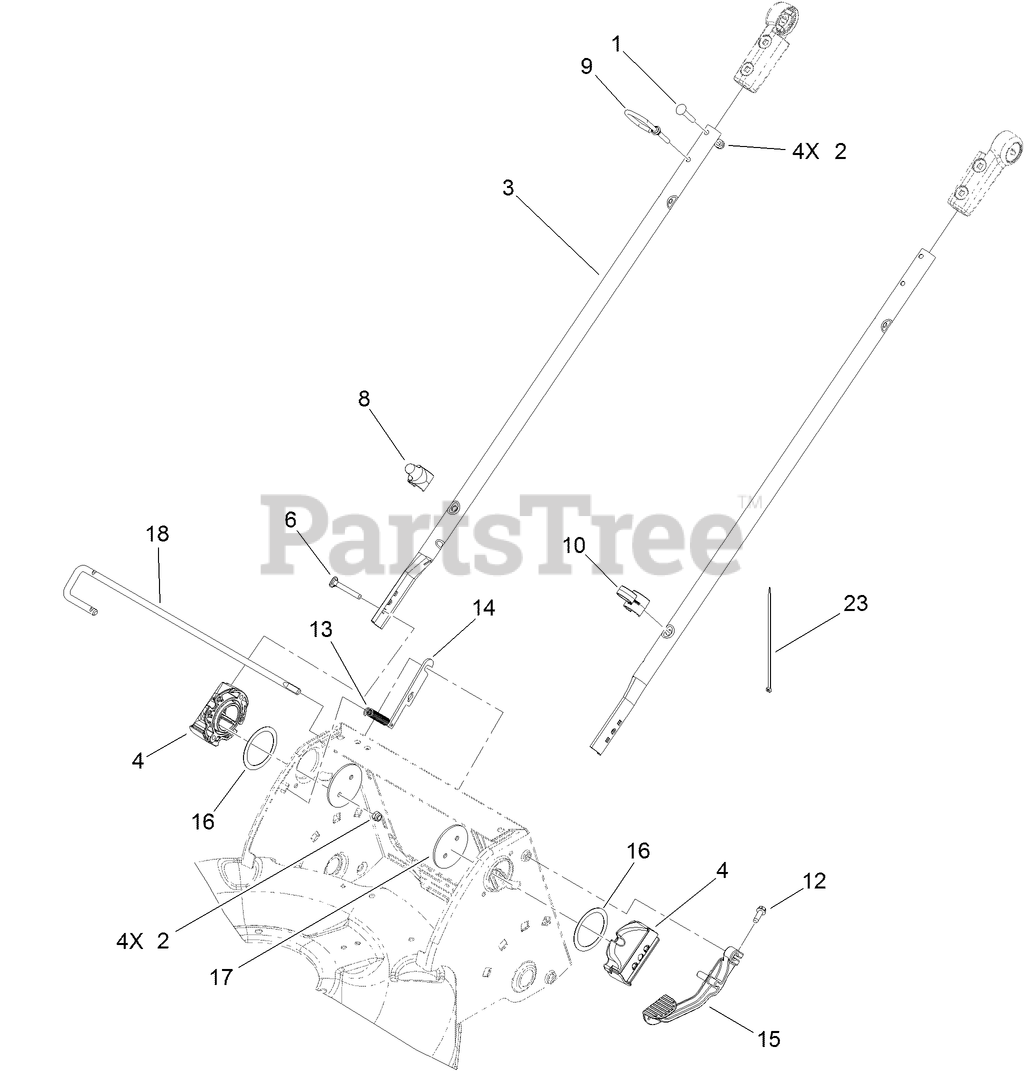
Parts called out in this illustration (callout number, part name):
1	SCREW-CARR
2	NUT-LOCK, NI
3	TUBE-LOWER
4	MOUNT-HANDLE
6	SCREW
8	GUIDE-ROPE, LOWER
9	GUIDE-ROPE, UPPER
10	GUIDE-CABLE
12	SCREW-HWHTF
13	SPRING-EXTENSION
14	PLATE-ROD, RELEASE
15	LEVER-RELEASE
16	WASHER-NYLON
18	ROD-RELEASE, HANDLE
23	TIE-CABLE
